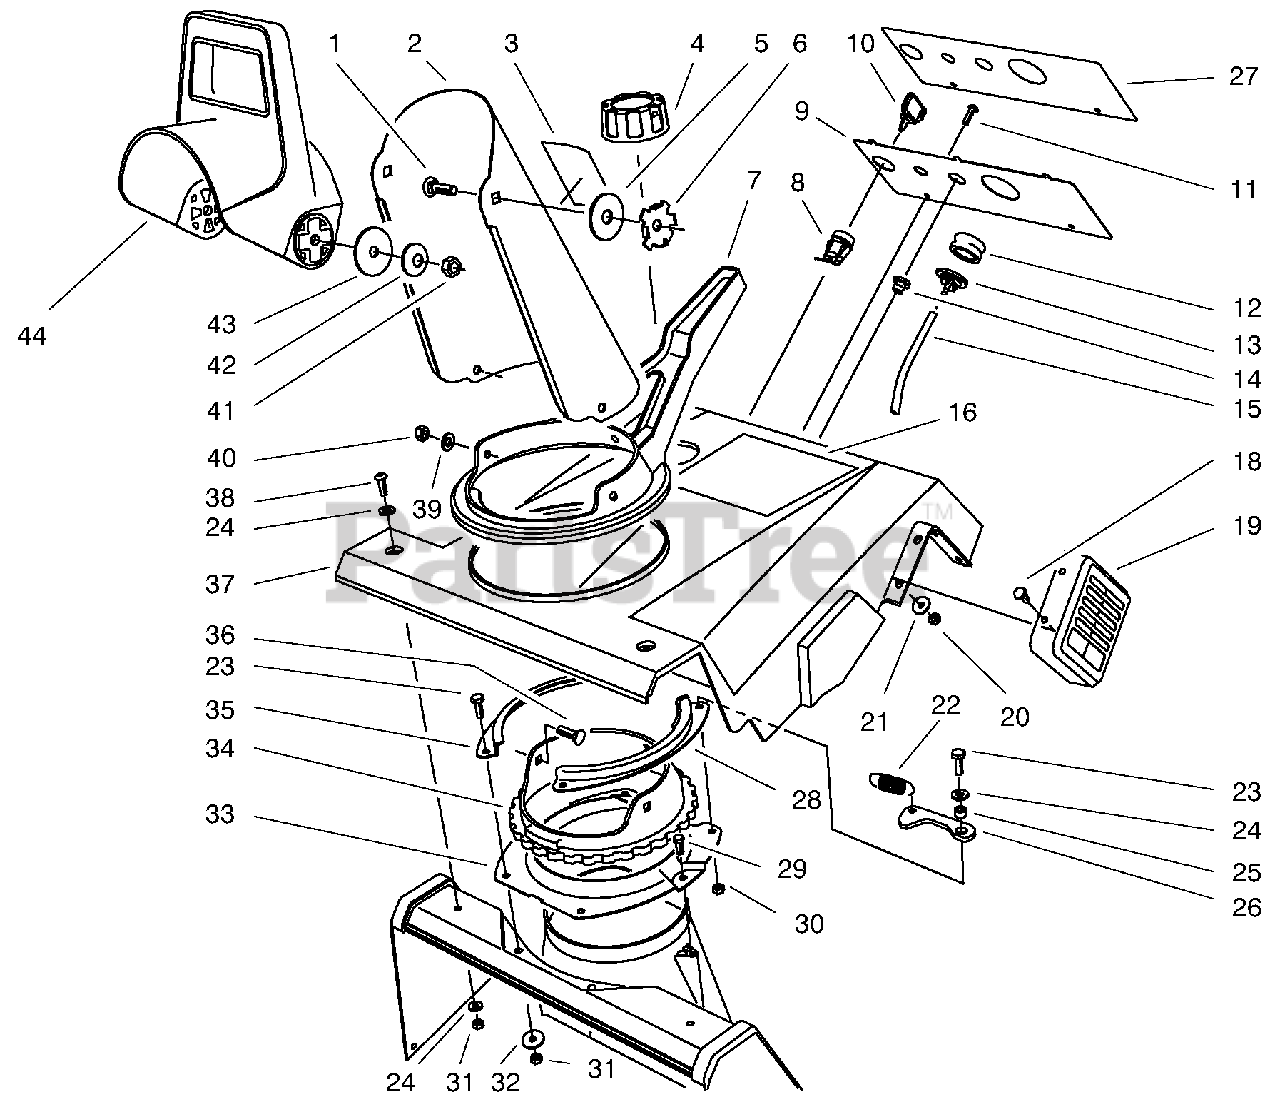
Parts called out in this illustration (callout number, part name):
1	Bolt-Carriage
2	Discharge Chute Assembly (Incl. Ref. #3)
3	Decal- Danger
4	Gas Cap Assembly
5	Washer-Rubber
6	Plate-Friction
7	Handle-Chute
8	Switch-On-Off
9	Panel-Control (Model No. 28221)
10	Key-Ignition
11	Screw-Slotted Flange Hd.
12	Bulb-Primer
13	Body- Primer
14	Guide-Rope
15	Hose-Primer
16	Decal-320 (Model No. 28221)
18	Screw-Hex. Hd.
19	Guard-Muffler
20	Nut- Lock
21	Washer-Flat
22	Spring-Extension
23	Screw-Hex. Hd.
24	Washer-Flat
25	Spacer-Detent Arm
26	Arm-Detent
27	Decal-Control Panel (Model No. 28221)
28	Retainer-Chute Ring L.H.
29	Screw-Hex. Flange Hd.
30	Nut-Lock
31	Nut-Lock
32	Washer-Flat
33	Support-Chute Ring
34	Ring-Chute
35	Retainer-Chute Ring R.H.
36	Bolt-Carriage
37	Shroud-Upper
38	Screw-Pan Hd.
39	Washer-Flat
40	Nut-Keps
41	Nut-Lock
42	Washer-Belleville
43	Washer-Flat
44	Deflector-Discharge
